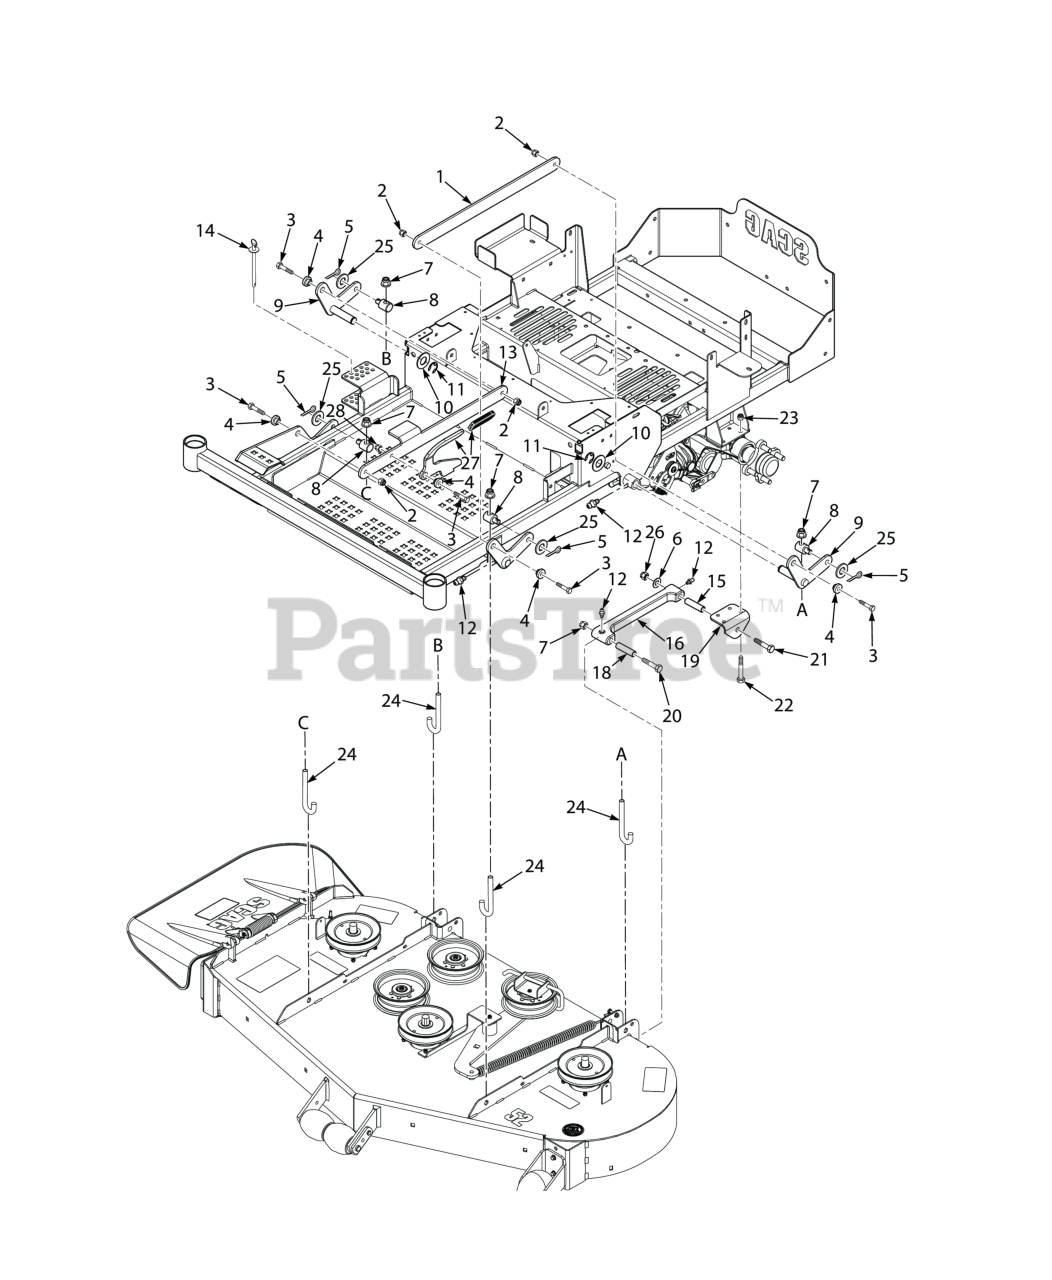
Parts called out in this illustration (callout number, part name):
1	Link, Deck Lift - LH
2	Nut, Flange Elastic Stop Nut, 3/8-16
3	Bolt, Hex Head 3/8-16 x 1-1/4", Kawasaki FX / FS
4	BUSHING, SPEED ADJUSTMENT LEVER
5	Pin, Cotter 3/16 x 1.0"
6	Flatwasher, 1/2 - .531 x 1.062 x .095
7	HEX LOCKNUT, ELASTIC STOP, 1/2-13
8	Joint, Swivel
9	Lift Bellcrank Weldment
10	Flatwasher, 3/4 (.766 x 1.250 x .060)
11	RETAINING RING, 3/4" EXTERNAL "E"
12	GREASE FITTING, STR. 1/4-28 SELF TAP.
13	Link, Deck Lift - RH
14	Pin Assembly, Deck Height
15	Spacer, Pusharm - Axle
16	Pusharm Assembly, LH
17	Pusharm Assembly, RH
18	Spacer, Pusharm - Deck
19	Bracket, Push Arm Link
20	Bolt, Hex Head 1/2-13 x 3-1/2"
21	Bolt, Hex Hd. 1/2-13 x 2-1/2" (lower)
22	Bolt, Hex Head 5/16-18 x 3.00"
23	HEX NUT, ELASTIC STOP LOCK, 5/16-18
24	Rod, Deck Lift
25	Flatwasher, 5/8" (.656 x 1.312 x .095")
26	Locknut, Hex 1/2-13 Center Lock
27	Lever Assembly (incl. Grip)
28	HEX NUT, ELASTIC STOP LOCK, 3/8-16
